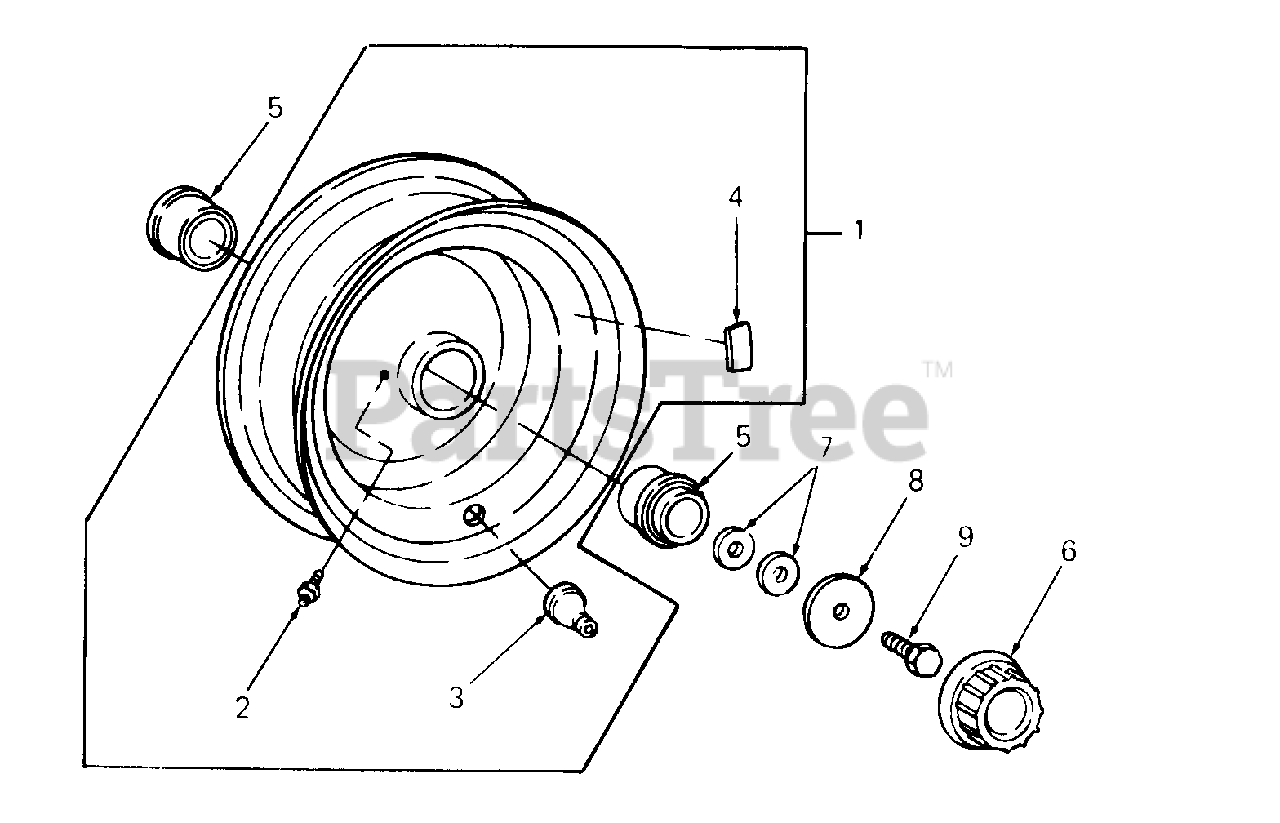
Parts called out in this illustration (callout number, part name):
1	Wheel Assy, Front
2	Fitting, Lube
3	Valve, Tubeless Air
4	Label, Inflation
5	Bearing, Wheel Ball
6	Cap, Hub
7	Washer, Flat, .531 X 1.25 X .100 Thk
8	Washer, Flat, .535 X 1.92 X .060 Thk
9	Bolt, Patch, 1/2-13 X 1.0 Lg GR5
